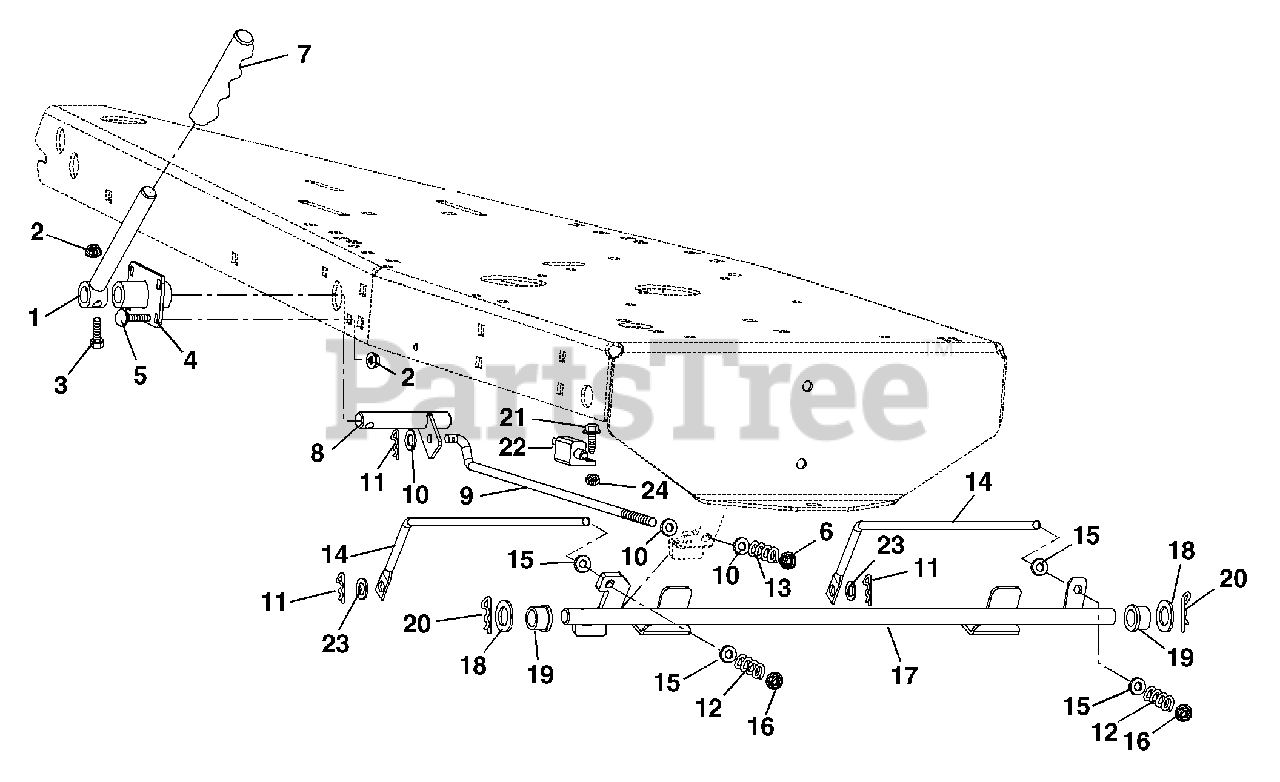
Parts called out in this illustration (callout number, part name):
1	WMT, HANDLE
2	NUT-LK-TOP-FLG .31-18 BLKZC
3	@BLT-HEX .31-18X1.50 GR5 YWZC
4	WMT, HANDLE PIVOT
5	BLT-RDHDSQNK .31-18X.75 G5BZ
6	NUT-LK-TOP-FLG .38-16 BLKZC
8	WMT, PIVOT ARM
9	ROD, ARM-LOCKING
10	@WSHR-FL-STL.406X.812X.065 YWZ
11	PIN-HAIR, ENDRIES #25 YWZC
12	SG-COMP .045X.50X1.187
13	SG-COMP .063X.53X1.187
14	ROD, BRAKE ACTUATING
15	@WSHR-FL-STL.344X.688X.065YWZC
16	@NUT-LK-TOP-FLG .31-18 YWZC
17	SHAFT, BRAKE-WELDMENT
18	WSHR-FL-STL .890X1.500X.1196YZ
19	BSHG-FLG .630X1.000X.625 NY
20	PIN, SPRING CLIP
21	SCR-TAP 10-24X.75 HWH TR YWZC
22	SWITCH- SINGLE POLE N.O.
23	@WSHR-FL-STL.406X.812X.065 YWZ
24	@NUT-LK-NYL 10-24 W/INSRT YWZC
